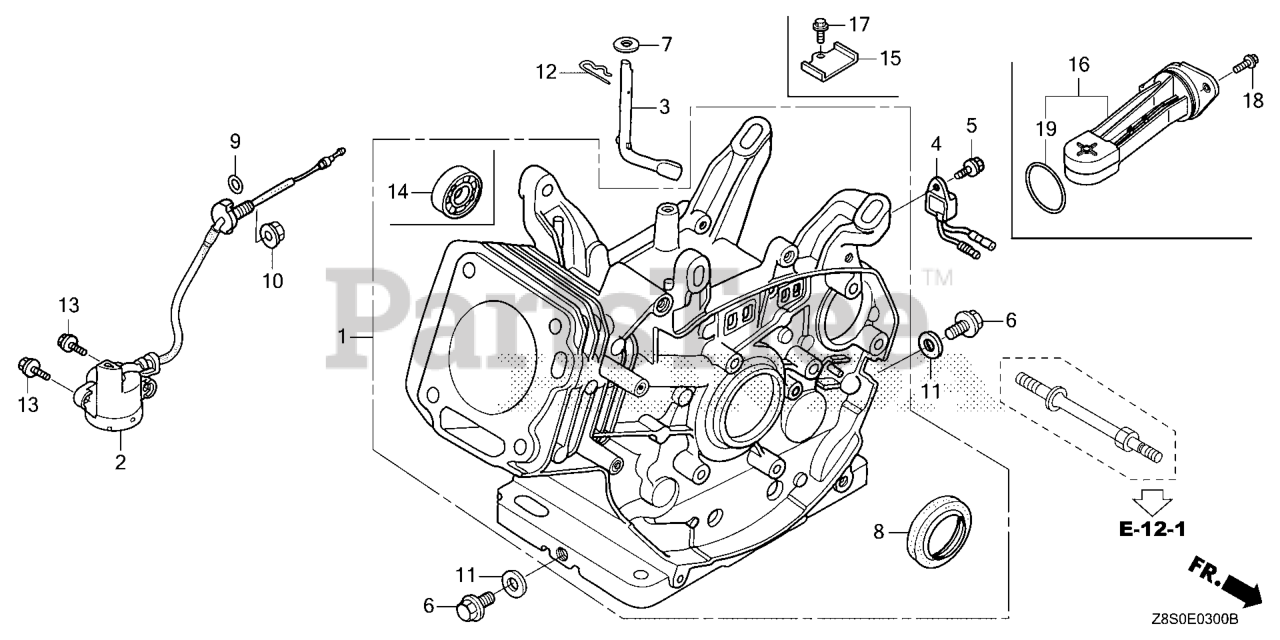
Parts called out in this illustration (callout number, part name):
1	CYLINDER ASSY.
2	SWITCH ASSY., OIL LEVEL
3	SHAFT, GOVERNOR ARM
6	BOLT, DRAIN PLUG
7	WASHER (8.2X17X0.8)
8	OIL SEAL (30X46X8) (NOK ASIA)
8	OIL SEAL (30X46X8)
9	O-RING (14MM) (ARAI) Use up to Engine SN 2949254.
10	NUT, FLANGE (10MM)
11	WASHER, DRAIN PLUG (12MM)
12	PIN, LOCK (10MM)
13	BOLT, FLANGE (6X12) Use up to Engine SN 1543277.
14	BEARING, RADIAL BALL (6202)
